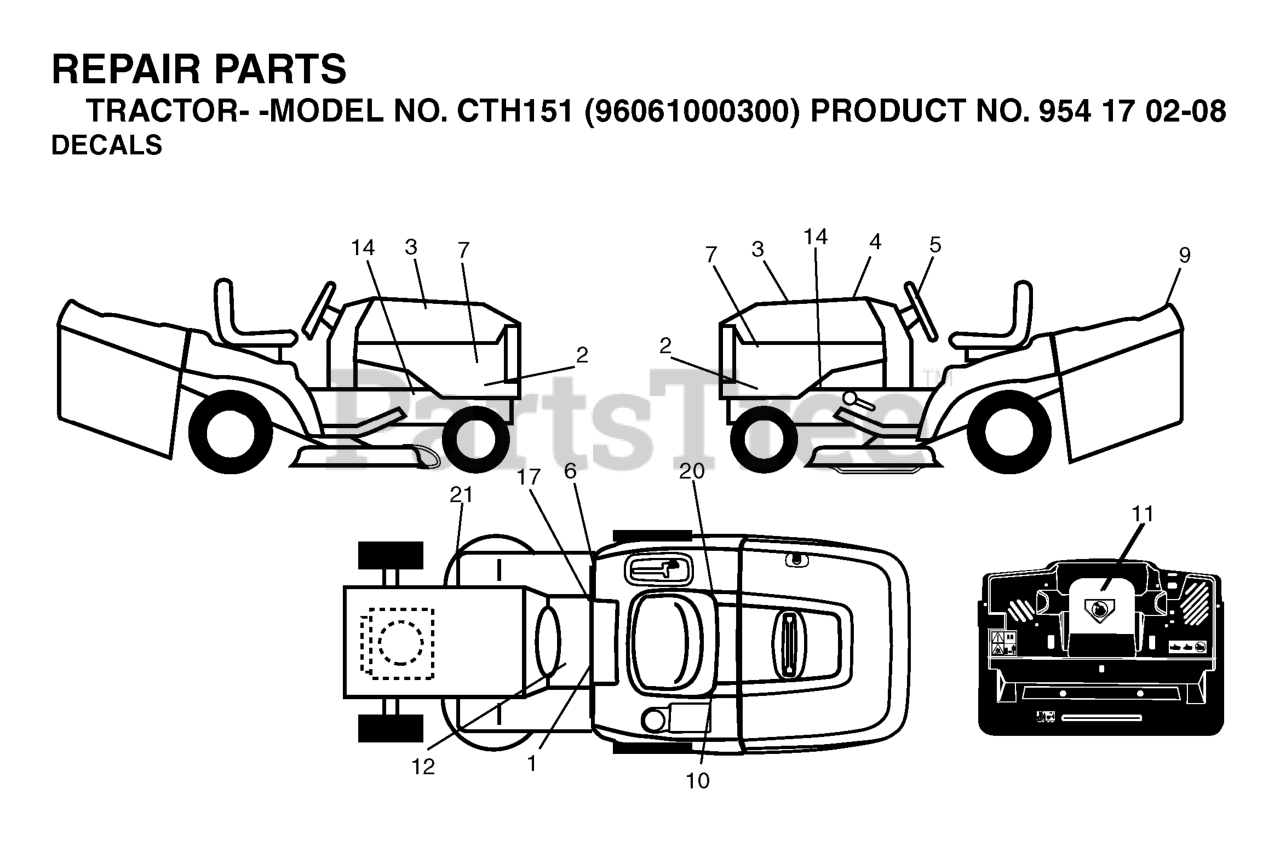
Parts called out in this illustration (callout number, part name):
1	DECAL READ OWNER'S MAN SYMS
5	DECAL.STEERING.HUSQ.BLUE
6	Decal, Fender 100 DB/CE
7	DECAL.HOOD.HUSQVARNA.INTERNATI
10	DECAL BTRY SYMBOLS
11	DECAL.INTERNATIONL.CUTFINGER
12	DECAL
17	DECAL PARK BRAKE
20	DECAL.BYPASS.FENDER.CRD.LT.YT
